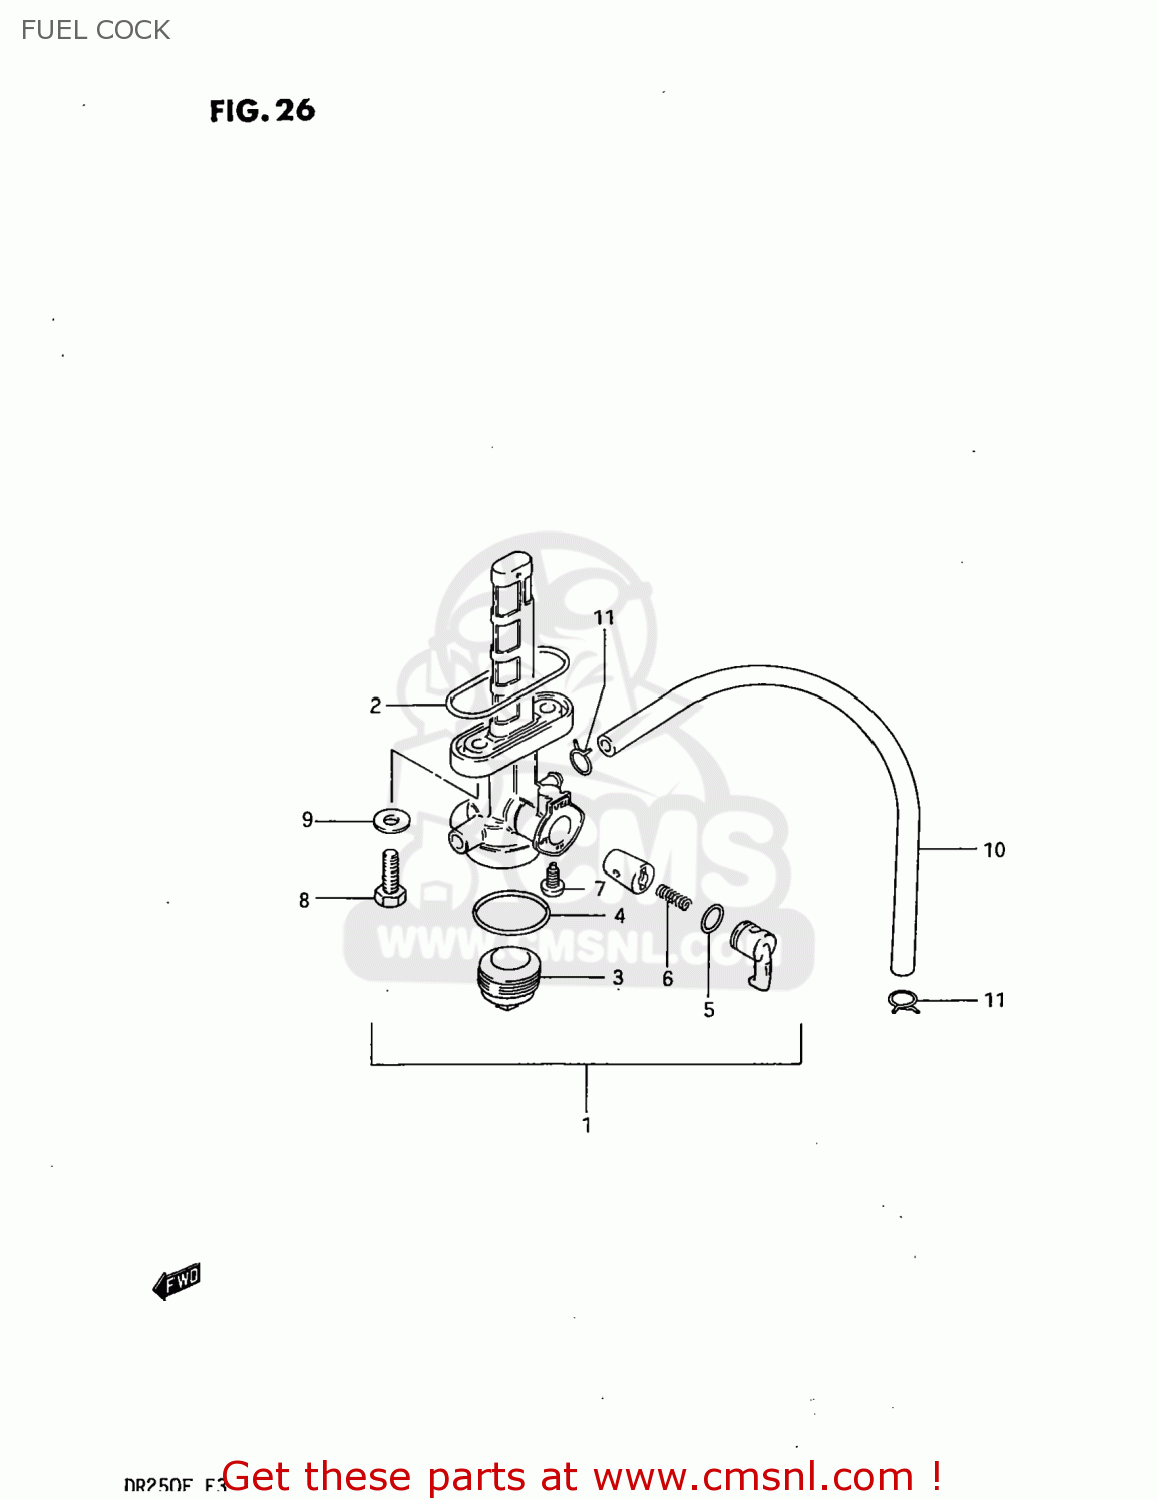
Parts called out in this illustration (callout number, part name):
1	COCK ASSEMBLY,FUEL
2	O RING,FUEL COCK
3	CUP,STRAINER
4	GASKET,FILTER (NAS)
5	O-RING
6	SPRING
7	SCREW
8	BOLT(6X20)
9	GASKET
10	HOSE
11	CLIP
